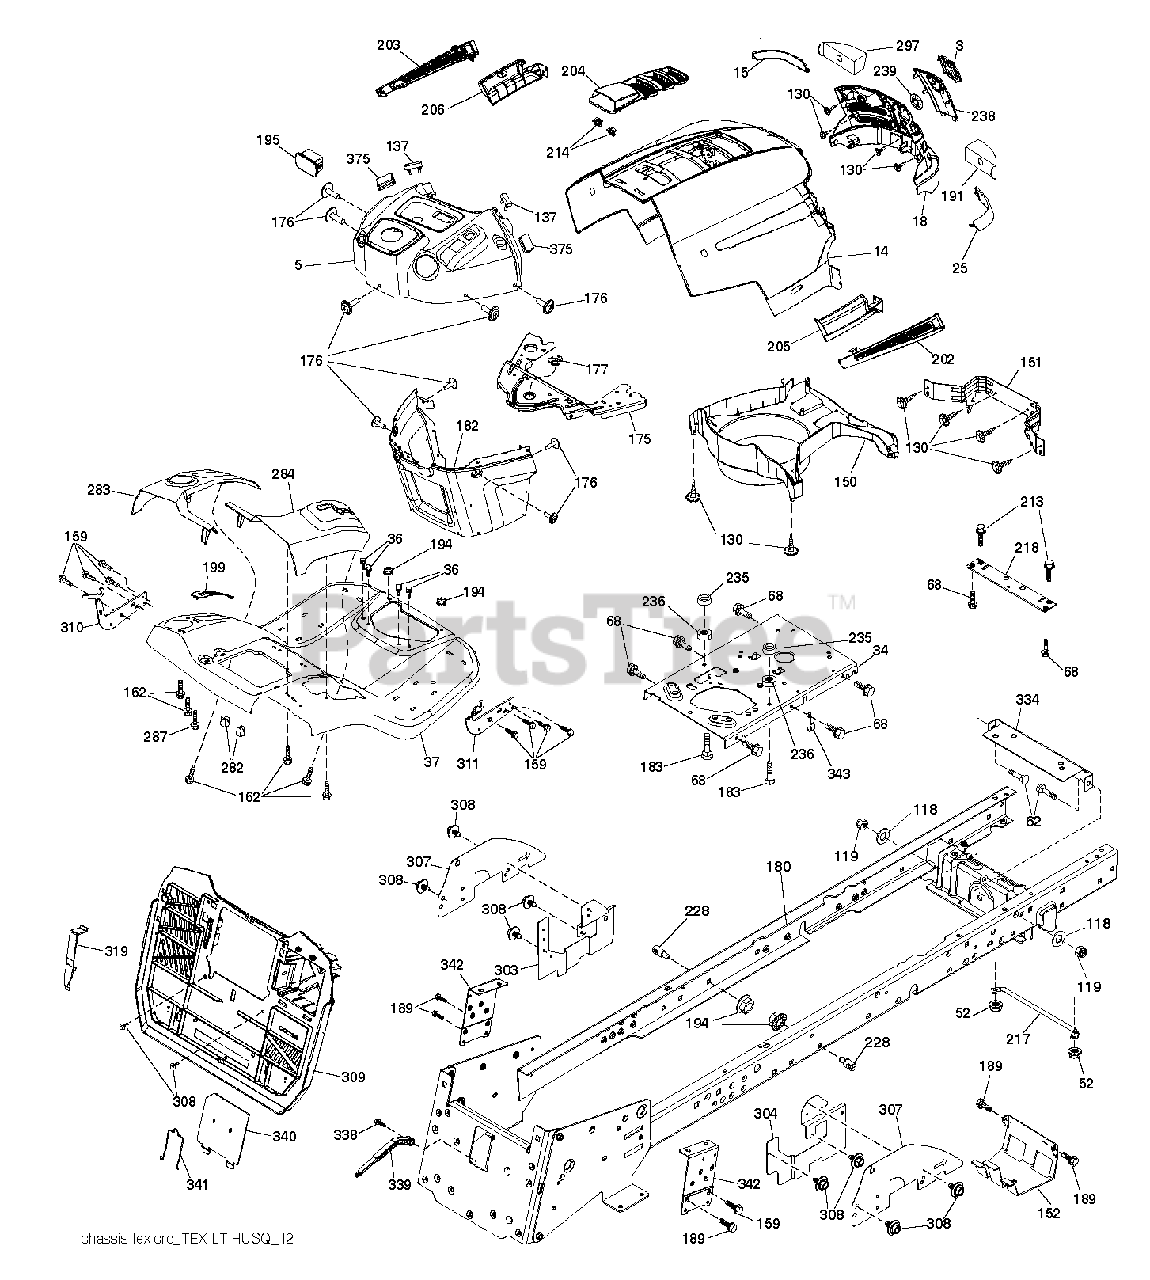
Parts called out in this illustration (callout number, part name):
3	LOGO.HUSQ.GT.LT.CROWN.H
5	DASH.UPPER.HUSQ LT CABLE.CLUTC
14	HOOD.HUSQVARNA.LT.ORANGE
15	LENS.HUSQVARNA LT.RH
18	GRILLE.SVC.HUSQVARNA.GREY
25	LENS.HUSQVARNA LT.RH
34	PLATE.ENGINE.10GA.CRD.GENII
36	SCREW 5/16"
37	FENDER.TEX.SRD.CRD.FRN.GUARDS
52	LOCKNUT
62	BOLT D
68	SCREW LT
118	WASHER
130	SCREW.#10 X 0.750.BOS
137	BUMPER DASH
151	BRACKET PIVOT
152	SHIELD.BROWNING.W/TEX
162	SCREW.HI-LO.CONSOLE
175	CROSSMEMBER
176	SCREW.#10-24X5/8.RN.QU
177	BUSHING STEERING
180	CHASSIS WLDT TEX CRD
182	DASH.LOWER.PREDATOR LT
183	BOLT.5/16-18X1-1/4 FULL THD
189	SCREW
191	INSERT.REFLECTIVE.RH.
194	NUT LOCK HEX FLANGE 5/16-18
195	PLUG.TEX.DASH.SVC.MINDER.GREY
199	PLATE DECK LIFT
202	VENT.SIDE.HUSQVARNA.LT.RT
203	VENT.SIDE.HUSQVARNA.LT.LFT
204	SUBASM.TOP.VENT.HUSQ.LT
205	SKIRT.SIDE.HUSQVARNA.LT.RT
206	SKIRT.SIDE.HUSQVARNA.LT.LEFT
213	BOLT
214	CLIP.RETAINER.TINNER.
217	ROD.PIVOT.HOOD
218	X-PIECE.HOOD.STOP.NON/
228	STUD.FASTNER.W/ANTI-ROTATE
235	SPACER FENDER
236	NUT.CENTERLOCK.5/16-
238	TRIM.HUSQ LT.668
282	CLIP.RETAINER.CONSOLE.LT.HUSQ
283	CONSL.DECKLIFT.LH.SRD.TEX.CRD
284	CONSL.SHFT.PEDAL.RH.SRD.TEXCRD
287	SCREW 1/4X20
297	INSERT REFLECTIVE
303	SHIELD.LWR.LH.LT.30"CRDSRD.PNT
304	SHIELD.LOWER.RH.CRD.GEN.PNT
307	SHIELD.UPPER.CRD.SRD.ISO
308	BOLT, 5/16-18 X 1 3/4
309	BACKPLATE.TEX.CRD.GEN.1
310	LH.ADJUST.HANGER.BRACKET.ASM
311	RH.ADJUST.HANGER.BRACKET.ASM
319	BRACKET.ACTUATOR.BAGGER.SRD
334	BRACKET.ENGINE
338	BOLT BOLT SHOULDER
339	LEVER LEVER BAGGER
340	DOOR.PNT.BATTERY.TRY.TEX.CRD.
341	LATCH
342	SUPPORT SUPPORT FENDER
343	CLIP CLIP
375	BUMPER CLIP-ON. DASH 1"
